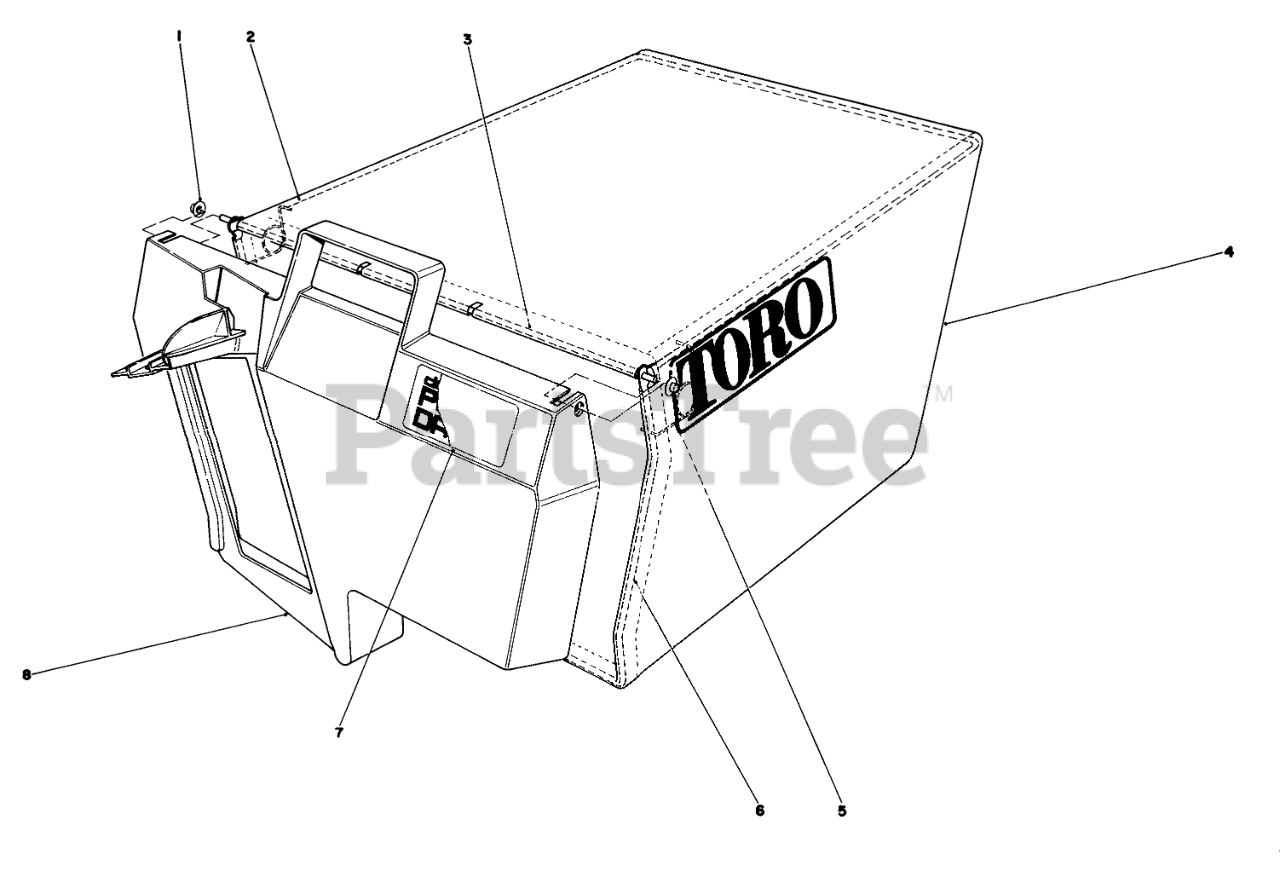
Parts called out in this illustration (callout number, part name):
1	NUT-PUSH
2	FRAME-BAG, UPPER
3	HINGE-DOOR, BAG
4	Bag
5	SPRING
6	FRAME-BAG
7	BAG DOOR DECAL
8	Door Grass Bag
